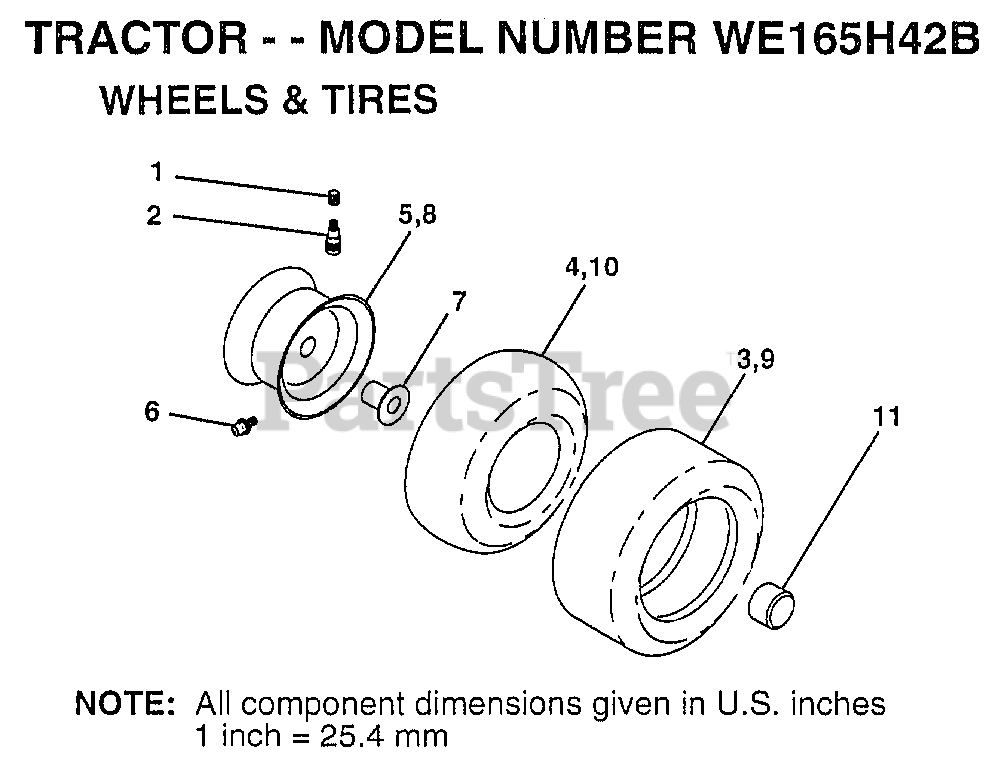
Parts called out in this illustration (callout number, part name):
1	VALVE CAP
2	VALVE STEM LT
4	TUBE.5.3/4.5/6
5	"RIM ASM 6"" FRT"
6	FITTING LT
7	"FLANGE, BEARING"
8	"RIM AS 8"" REAR"
9	TIRE.20X8-8
10	TUBE.18X9.5-8
11	HUB CAP
